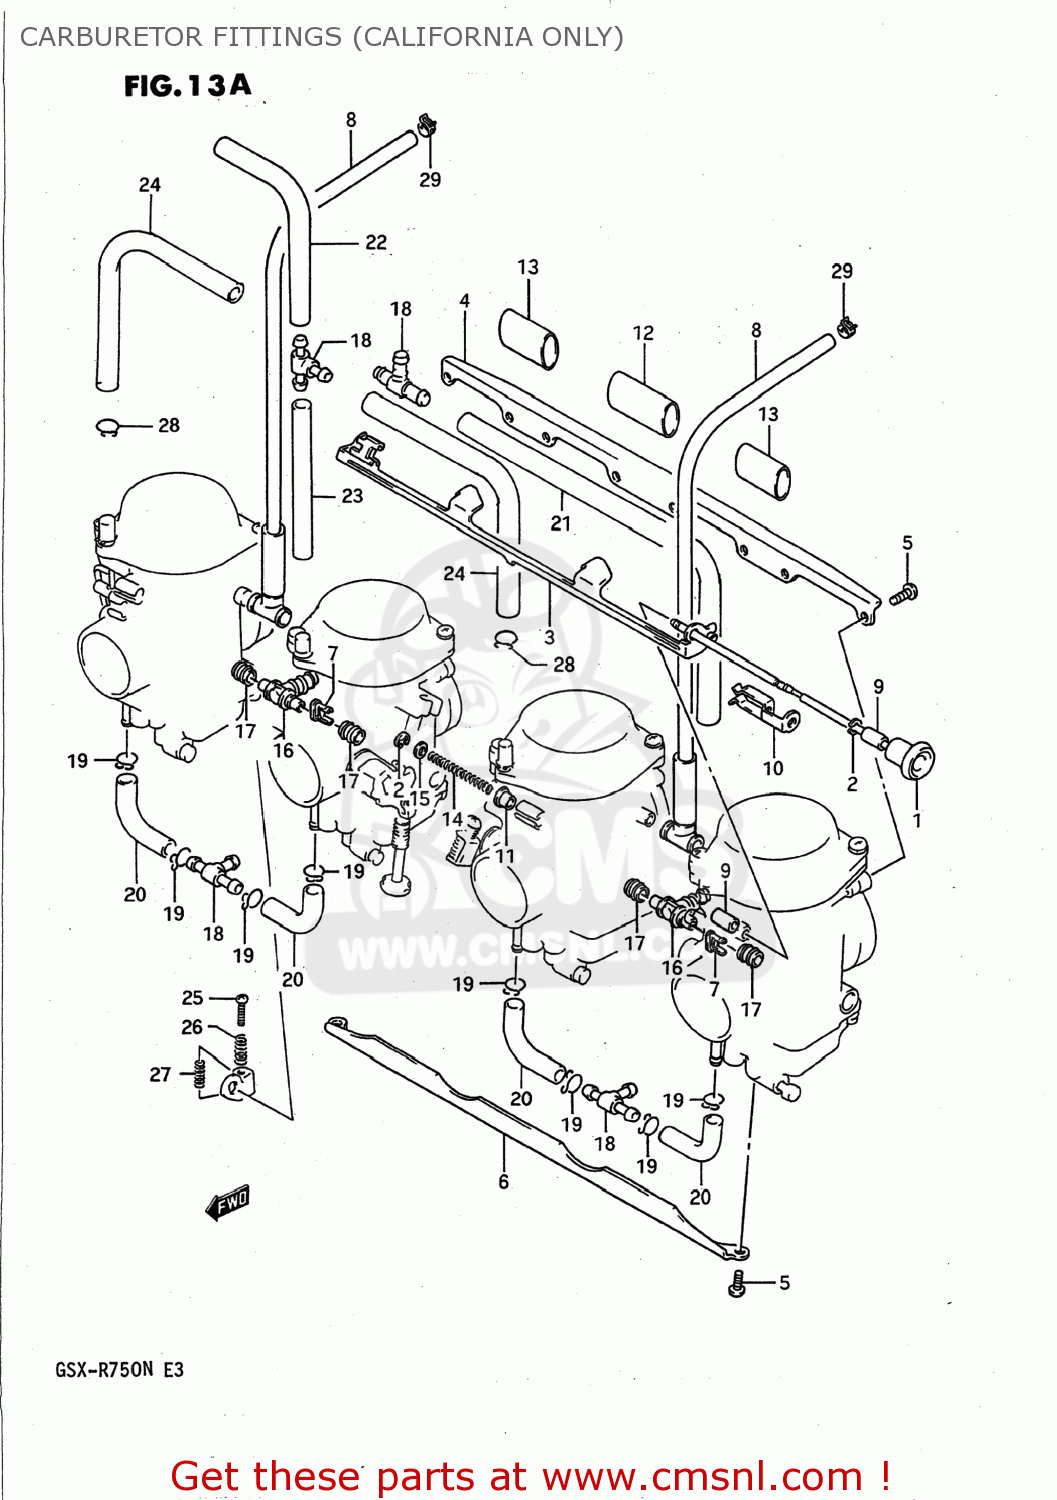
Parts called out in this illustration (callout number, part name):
1	SHAFT ASSY,STARTER
2	E RING
3	LEVER
4	PLATE
5	SCREW
6	PLATE
7	HOLDER
8	HOSE
9	SPACER
10	PLATE
11	RING
12	HOSE
13	HOSE
14	SPRING
15	WASHER
16	NIPPLE
17	SEAL
18	NIPPLE
19	CLIP
20	HOSE
21	HOSE
22	HOSE
23	HOSE
24	HOSE
25	SCREW
26	SPRING
27	SPRING
28	CLIP
29	CLIP
